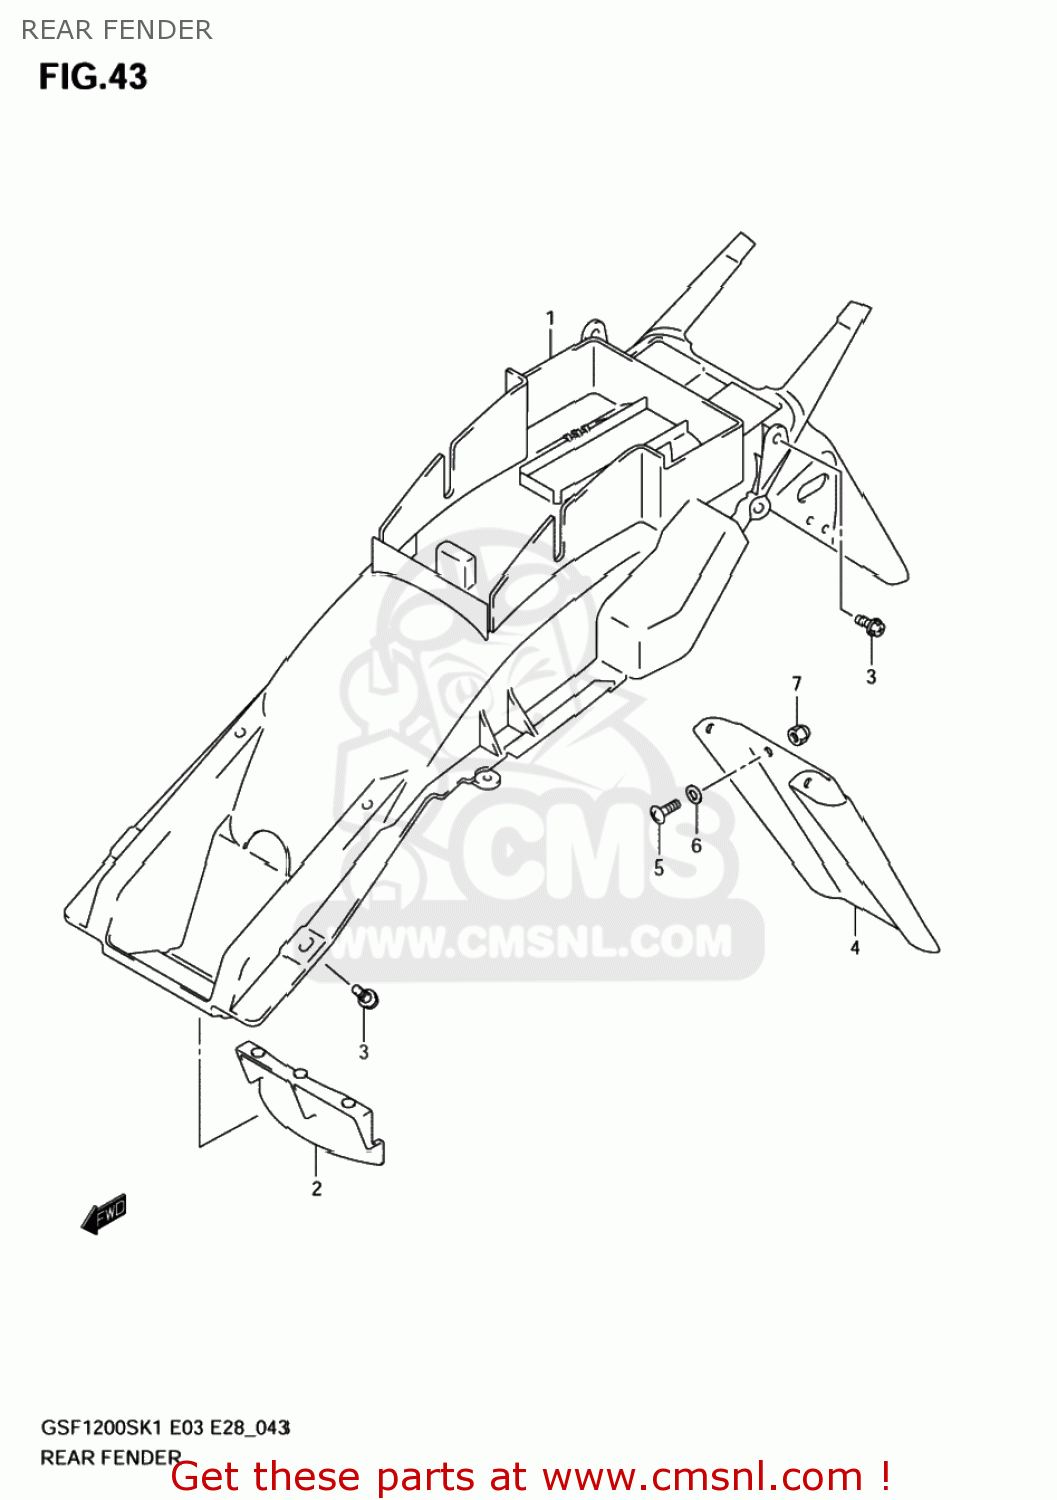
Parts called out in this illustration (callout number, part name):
1	FENDER,RR
2	MUDGUARD,RR FENDER
3	BOLT(6X16)
4	EXTENSION,RR FENDER
5	SCREW 6X12
6	WASHER(6.5X16X1.2)
7	NUT
